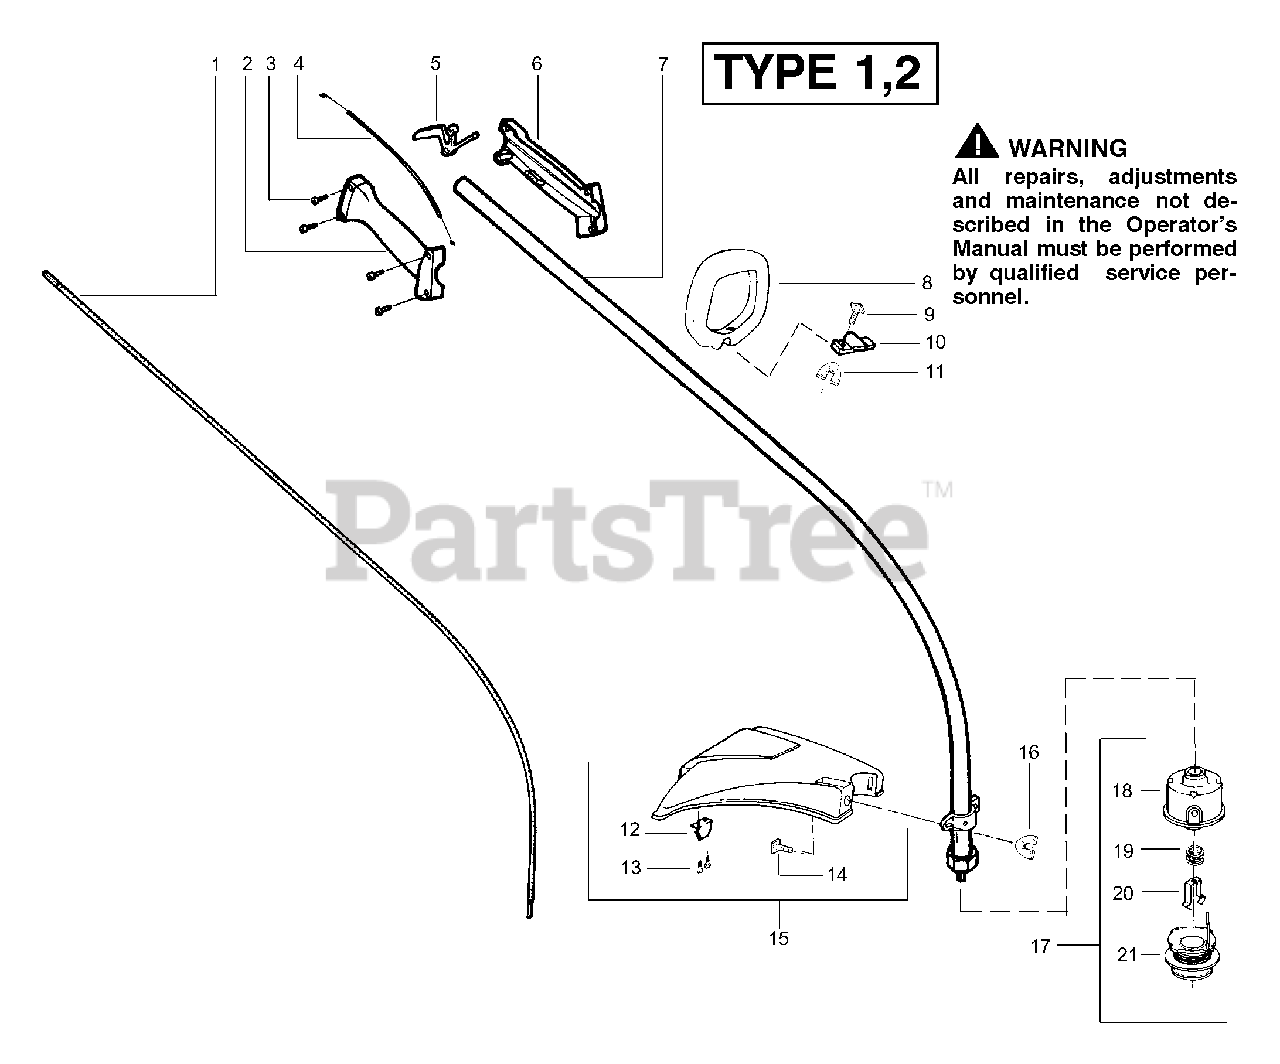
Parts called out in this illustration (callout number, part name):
1	Shaft Flex
2	Throttle Hsg. (Right)
3	Screw Throttle Hsg.
4	Assy Throttle Cable
6	Throttle Hsg. (Left)
7	Assy Drive Shaft Hsg.
8	Handle Assist
9	Bolt Handle/Shield
10	Clamp Handle
11	Wingnut Handle/Shield
12	Line Limiter
13	Screw Line Limiter
14	Bolt Handle/Shield
15	Kit Shield Assy
16	Wingnut Handle/Shield
17	Accy W/E TNG 5 Cutting Head
18	Assy Hub
19	Spring Compression
20	Clip Retainer Head
21	Accy W/E Spool w/Line
